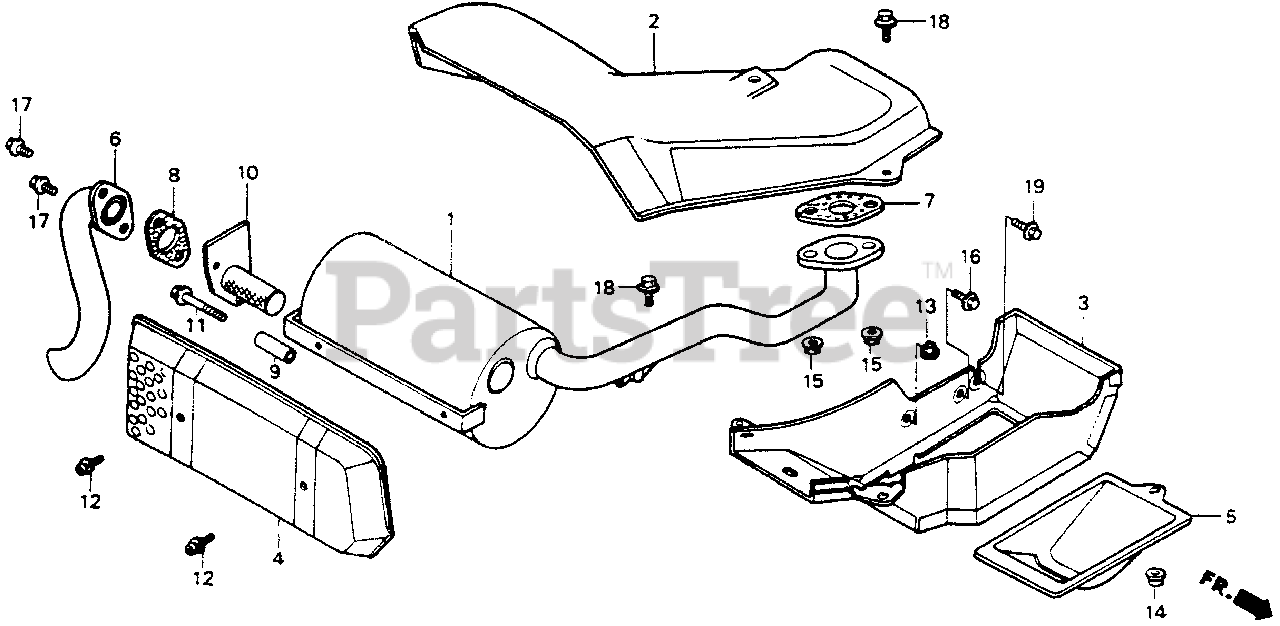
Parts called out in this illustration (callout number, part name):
2	PROTECTOR, HEAT (UPPER)
3	PROTECTOR, HEAT (LOWER)
4	PROTECTOR, MUFFLER
5	COVER, PROTECTOR (LOWER) (NOT AVAILABLE)
6	PIPE, TAIL (NOT AVAILABLE)
7	GASKET, EX. PIPE
8	GASKET, TAIL PIPE
9	COLLAR, MUFFLER JOINT
10	ARRESTER, SPARK
11	BOLT, FLANGE (8X55)
12	SCREW-WASHER (6X10)
13	NUT, FLANGE (6MM)
14	NUT, FLANGE (6MM)
15	NUT, FLANGE (8MM)
16	BOLT, FLANGE (6X10)
17	BOLT, FLANGE (6X10)
18	BOLT, FLANGE (6X12)
19	BOLT, FLANGE (6X16)
